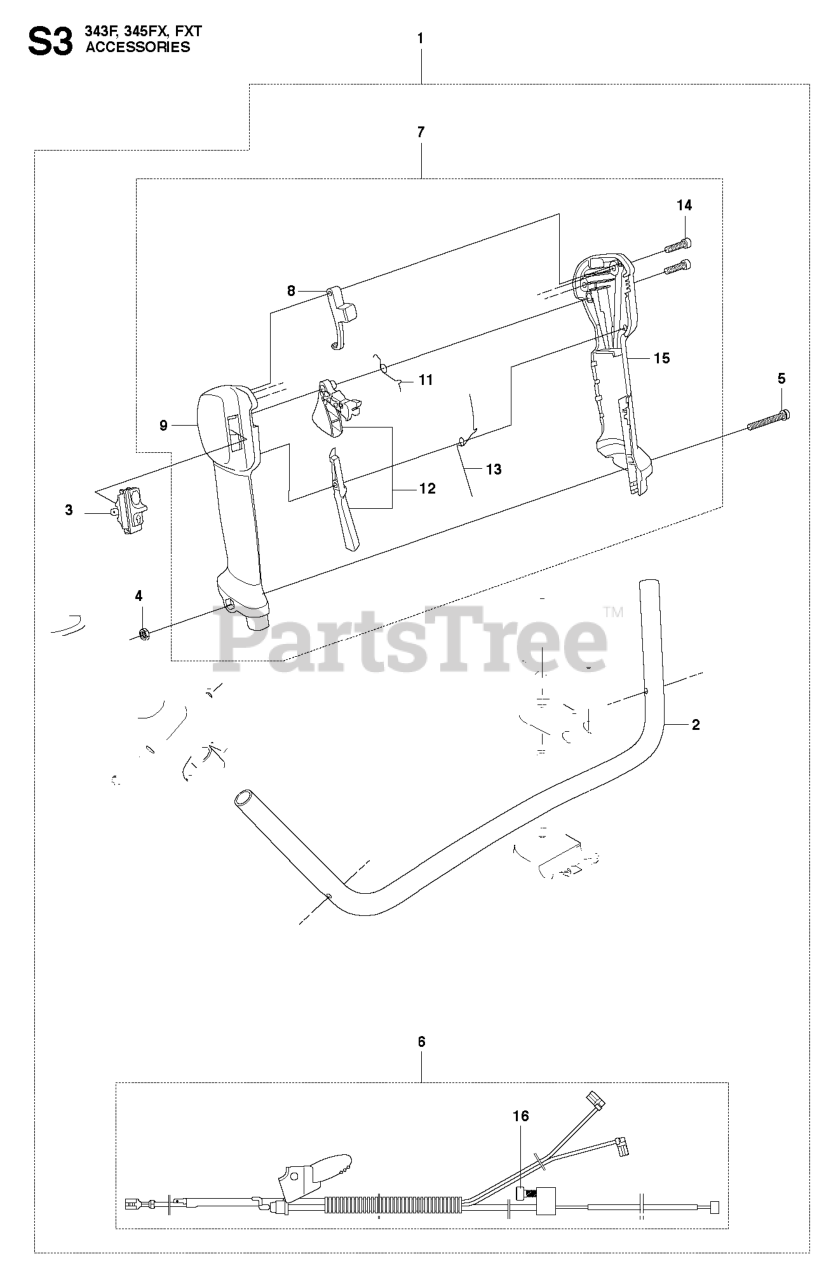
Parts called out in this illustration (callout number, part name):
2	HANDLE
5	SCREW
6	WIRING ASSY
7	THROTTLE HANDLE ASSY
8	LOCKOUT STARTER THROTTLE
9	HANDLE HALF LEFT
12	THROTTLE CONTROL
15	HANDLE HALF RIGHT
16	SCREW
